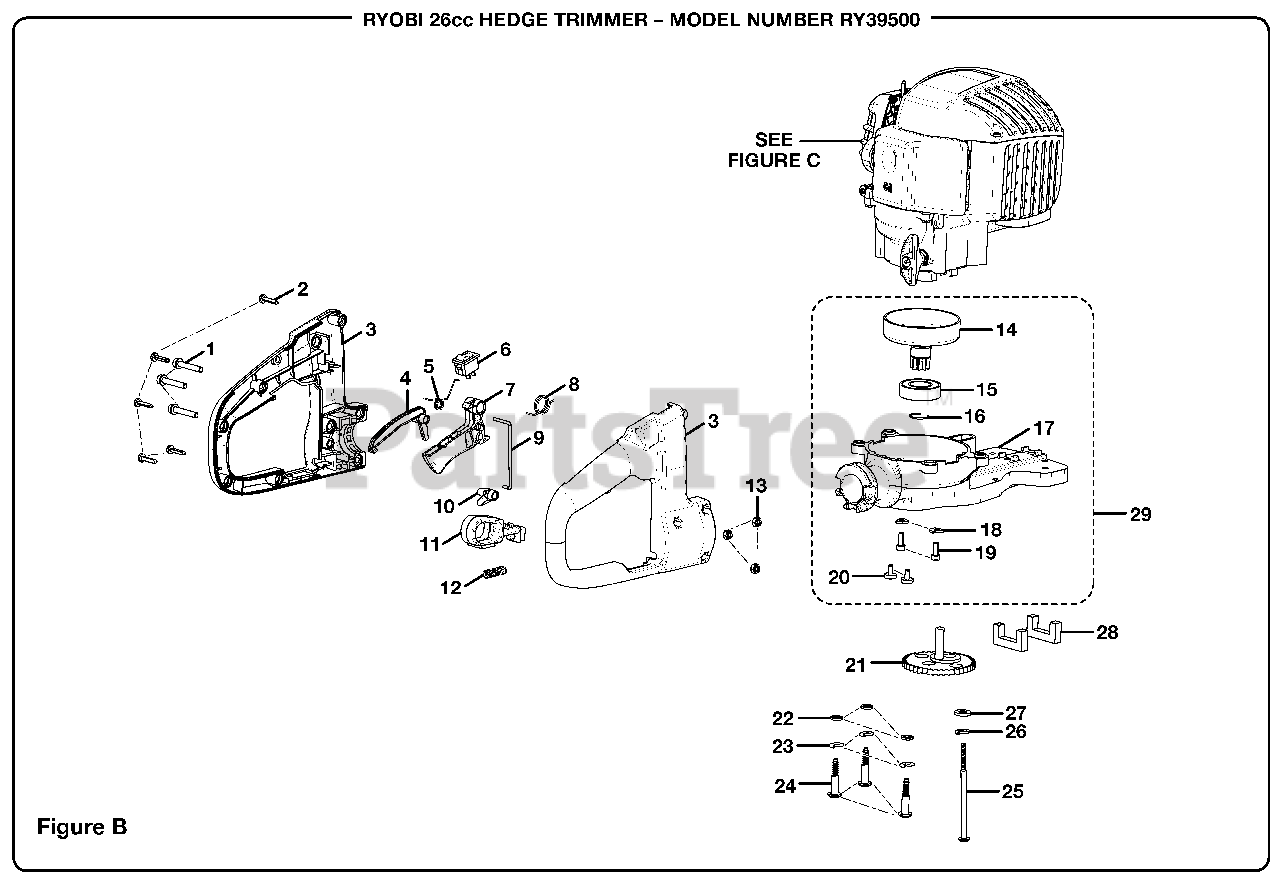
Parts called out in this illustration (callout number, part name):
1	Screw
2	Screw
3	Rear Handle Housing Assembly
4	Interlock Level
5	Trigger Lock Spring
6	Switch
7	Throttle Trigger
8	Trigger Spring
9	Lock Level
10	Rotate Level
11	Rotate Lock Puller
12	Rotate Lock Spring
13	Hex Nut
14	Clutch Drum Assembly
15	Ball Bearing
19	Screw
20	Screw
21	Big Gear Assembly
23	Spring Washer
24	Screw
25	Screw
26	Spring Washer
28	Felt Seal
29	Gear Box Assembly
